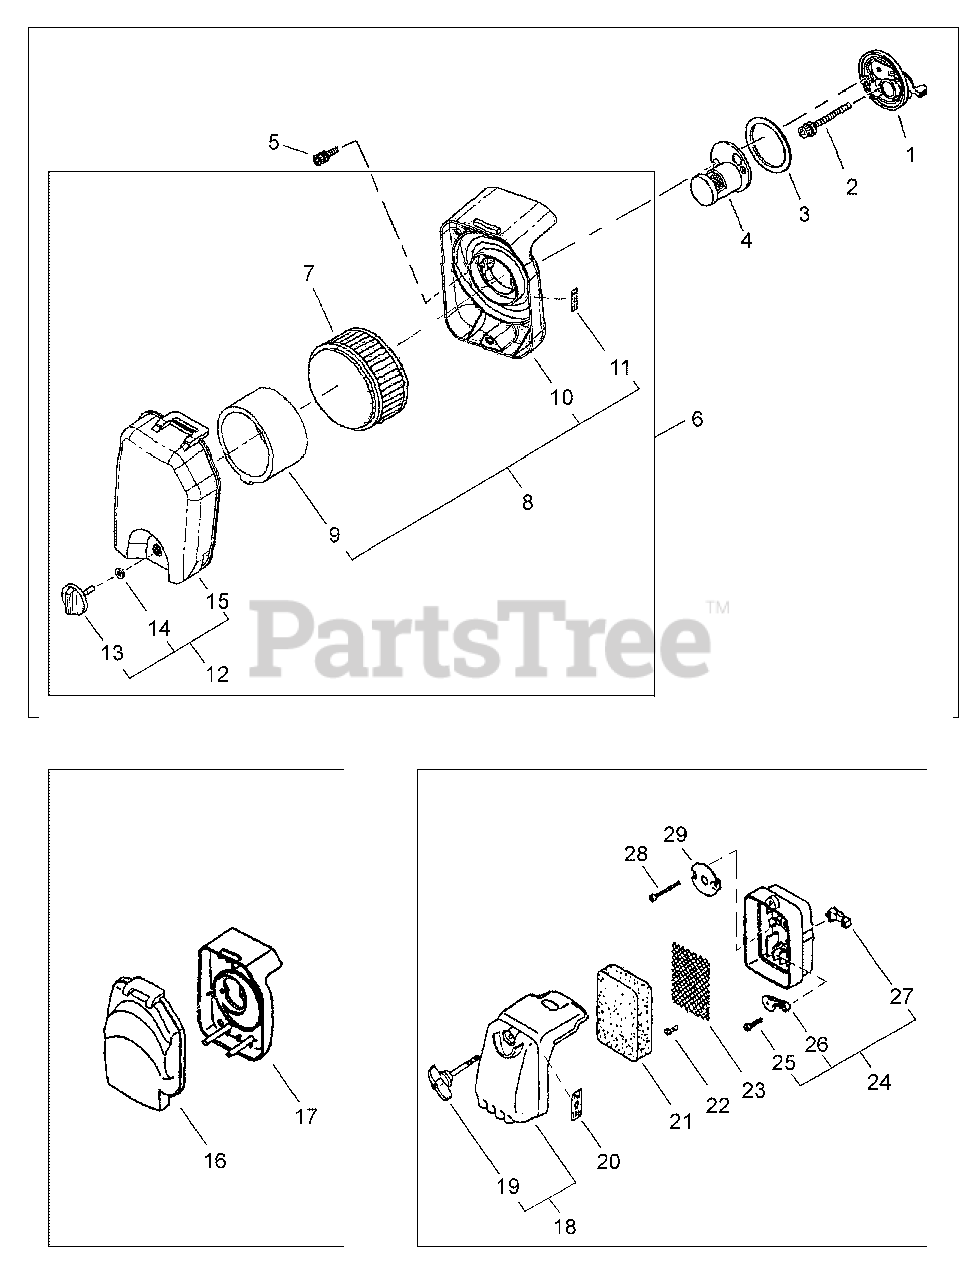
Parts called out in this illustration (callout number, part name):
1	CHOKE ASSY
2	SCREW - 5X50
3	GASKET
4	ADAPTOR, INTAKE
5	SCREW - 4X14
6	AIR FILTER ASSY - BLACK
7	FILTER, AIR
8	AIR FILTER KIT
9	PRE-FILTER
10	CASE, AIR FILTER
11	LABEL - CHOKE
12	AIR FILTER COVER ASSY
13	THUMBSCREW
14	WASHER - VINYL
15	COVER, AIR FILTER - BLACK
16	COVER, AIR FILTER
17	CASE, AIR FILTER
18	AIR FILTER COVER ASSY
19	THUMBSCREW
20	LABEL - CHOKE
21	FILTER, AIR
22	SCREW - TAPPING
23	SCREEN, SPARK ARRESTOR
24	CASE, AIR FILTER
26	PLATE, SHUTTER
27	LEVER, CHOKE
28	SCREW - 5X60
29	PLATE, PREVENT
